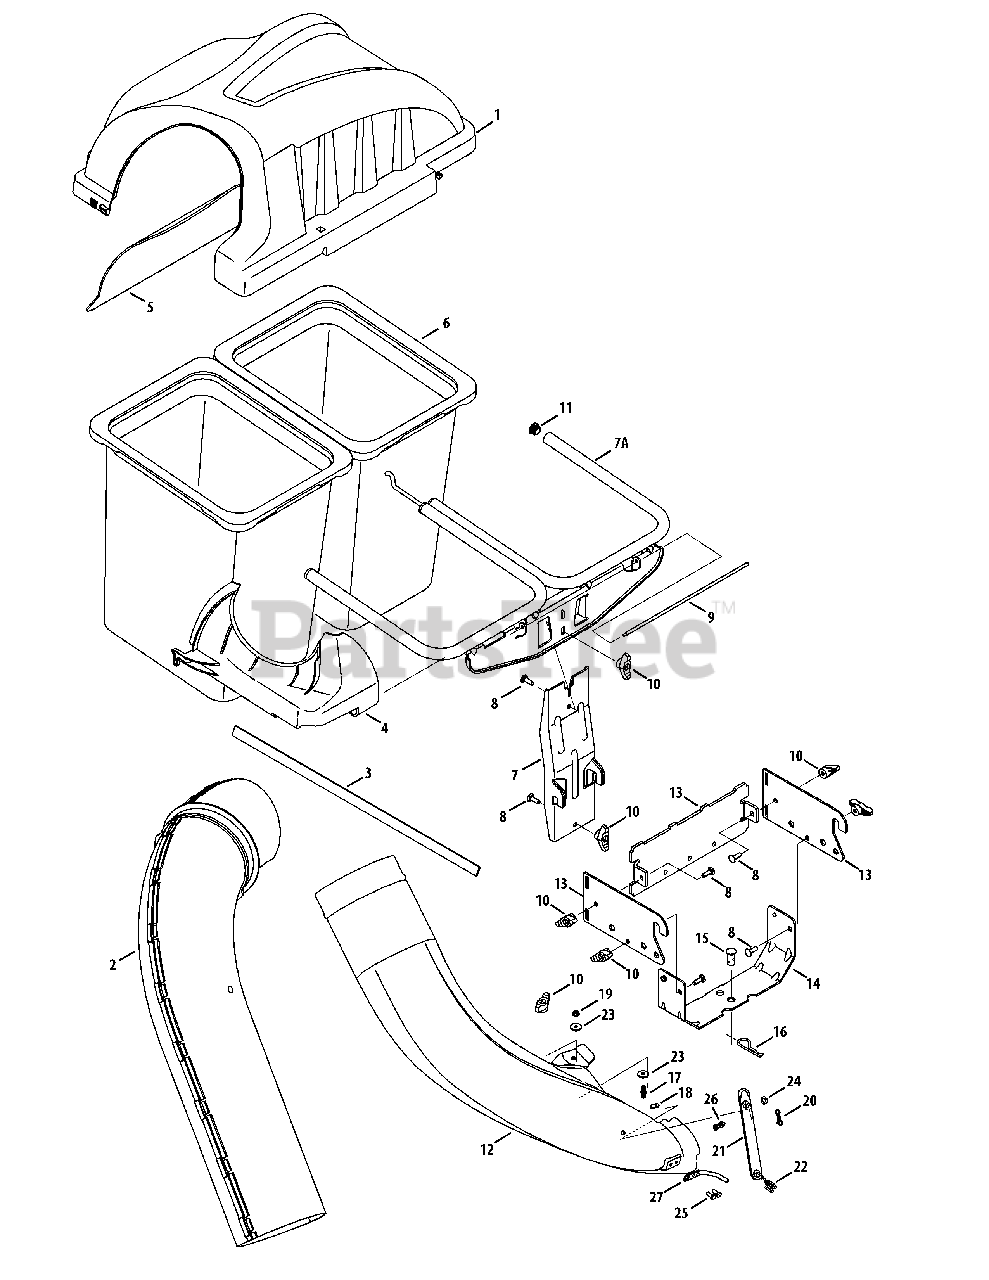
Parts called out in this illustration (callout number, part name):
1	Double Bagger Cover Assembly
2	Upper Chute Assembly
3	Self-Adhesive Foam Strip
4	Upper Chute Support
5	Bagger Cover Screen
6	Grass-bag Assembly
7	Vertical Support Bracket
7A	Double Bag Support Assembly
8	Carriage Screw, 5/16-18 x 1.00"
9	Cover Hinge Pin
10	Wing Knob, 5/16-18
12	Discharge Chute Elbow
13	Hitch Bracket Assembly
14	Universal Bracket Support
15	Clevis Pin, .62" Dia.
16	Internal Cotter Pin, .148 x 3.00
17	Attachment Pin
18	Clevis Pin, 5/16 x .75 Lg.
19	Flange Lock Nut, 1/4-20
20	Bow-Tie Cotter Pin, 72
21	Chute Strap, 6.00 Lg.
22	Torsion Spring Hook
23	Flat Washer, .265 x .938 x .120
24	Flat Washer, .344 x .620 x .033
25	Screw 1/4-20 X .62
27	Chute Rod, Lower
28	Flange Lock Nut, 3/8-16
